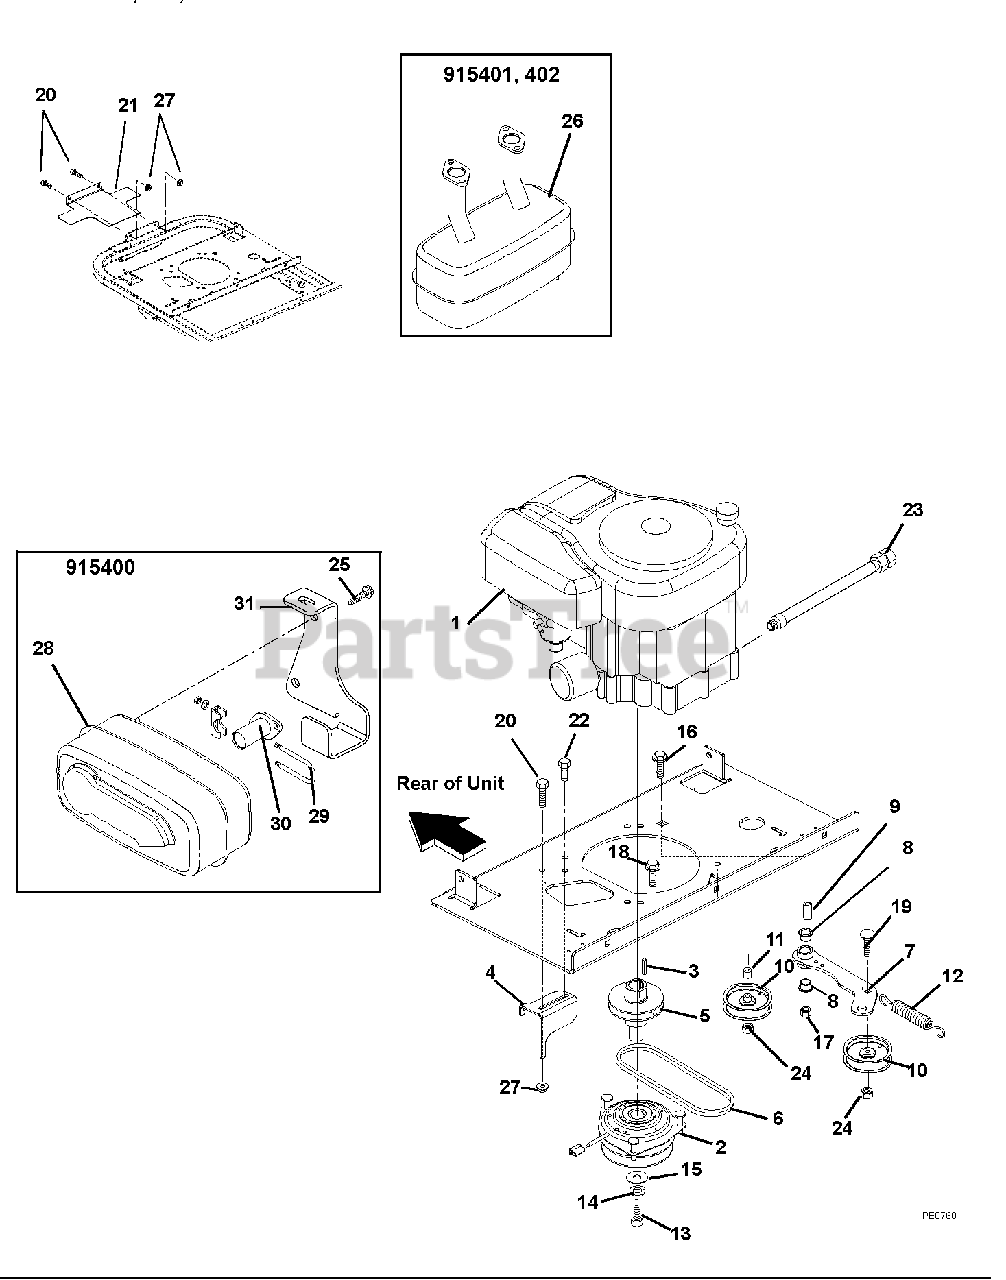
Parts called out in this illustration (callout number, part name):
1	Engine, 18hp Kohler (400)
2	Clutch, Electric
3	Key, Square .25 x 1.50 x .25 SAE 8630 OR SAE 1035
4	Clutch Stop
5	Extension Shaft
7	Weldment, Idler
8	Bushing, Flange .075 x .0875 x .625 x 1.125
9	Bushing, Sleeve .50 x .75 x 1.56
10	Pulley, Idler 4.00
12	Spring, Extension
13	Bolt, Hex .44-20 x 4.50 Grade 8
14	Washer, Locking .44 x .109 Regular
15	Washer, Flat Steel .469 x 2.00 x .25
16	Bolt-Hex .50-13 x 2.50 Grade 5
17	Nut, Locking Top Flange .50-13
18	Bolt-Round Head Square Neck .38-16 x 2.00 Grade 5
19	Bolt-Round Head Square Neck .38-16 x 1.25 Grade 5
20	Bolt-Hex .38-16 x 1.00 Grade 5
21	Heat Shield (401, 402)
22	Screw-Tapping .38-16 x 1.00 Hex Washer Head Thread Rolling YZ (400)
23	Tube, Oil Drain
24	Nut, Locking, Jam, Center .375-16
25	Screw, Tapping .25-20 x .50 Hex Washer Head (400)
26	Muffler (401, 402)
27	Nut-.38-16 Flange Nyloc (401, 402)
28	Muffler (400)
29	Muffler Clamp (400)
30	Weldment, Manifold (400)
31	Muffler Bracket (400)
32	Screw, Tapping .38-16 x 1.00 Hex Washer Head Thread Rolling YZ (400)
